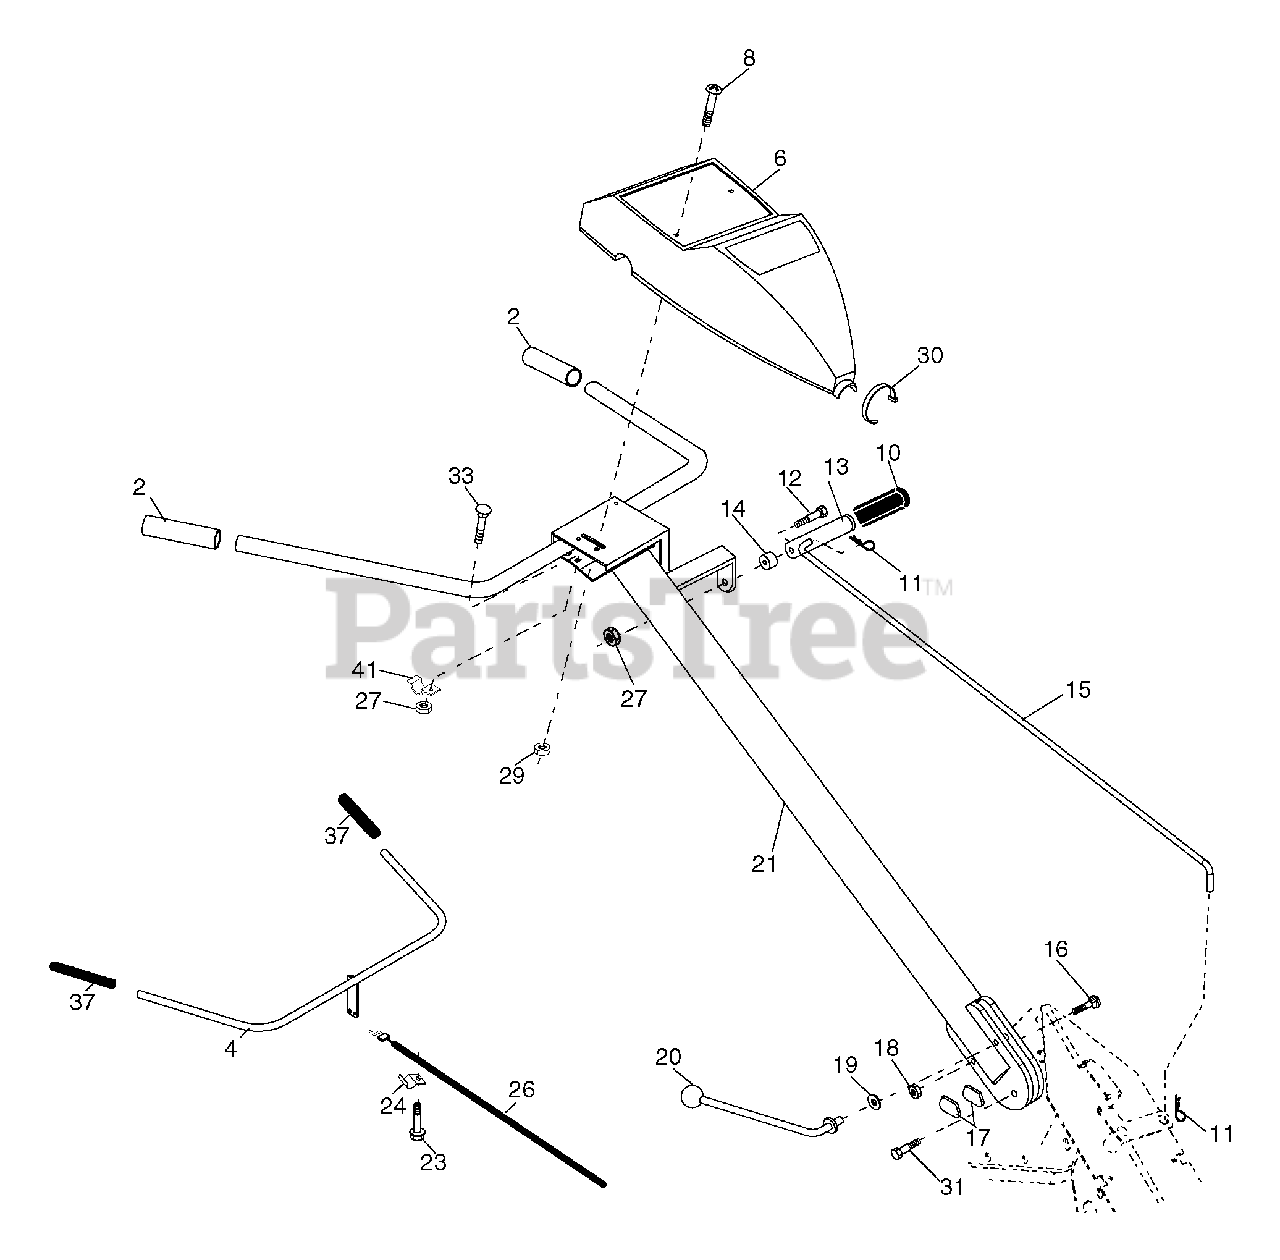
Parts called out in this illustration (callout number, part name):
1	Control, Throttle
2	Grip, Handle
4	Bar Assembly, Control
6	Panel, Control
8	Screw, Phd. #10-24
10	Grip, Handle
11	Clip, Hairpin
12	Bolt, Shoulder
13	Handle, Shift
14	Grommet, Rubber
15	Rod, Shift
16	Bolt, Carriage 3/8-16 x 1 Gr. 5
17	Lock, Handle
18	Nut, Crownlock 3/8-16 unc
19	Washer 13/32 x 1 x 11 Ga.
20	Lever, Lock, Handle
23	Screw, Hex Washer Hd. Slotted #10-24 x 1/2
24	Clip
26	Cable, Clutch
27	Nut Hex Flange 1/4-20 unc
29	Nut, Keps #10-24 unc
30	Tie, Cable
31	Bolt, Pivot
33	Bolt, Carriage 1/4-20 unc x 1/2
37	Grip, Bar, Control
41	Clamp, Bar, Control
